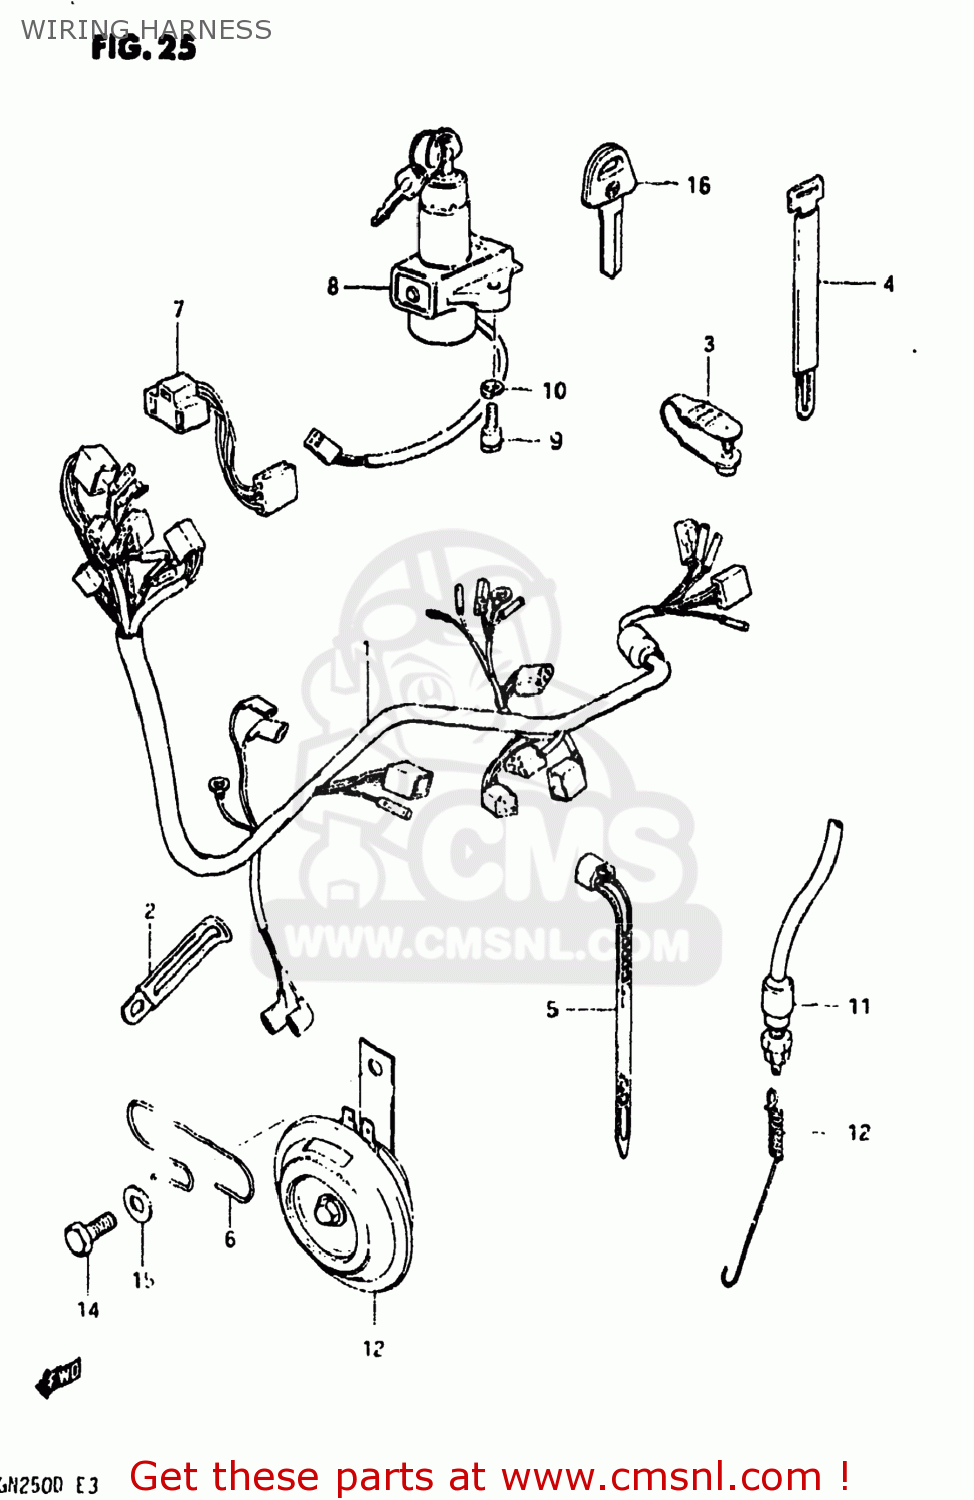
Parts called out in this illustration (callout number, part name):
1	HARNESS,WIRING
2	CLAMP
3	CLAMP,L:88
4	CLAMP
5	CLAMP(L:125)
6	CLAMP,WIRING HARNESS
7	LEAD WIRE,HEADLAMP
8	SWITCH ASSY,IGNITION
9	BOLT
10	LOCK WASHER
11	SWITCH ASSEMBLY,STOP LAMP
12	SPRING
13	HORN ASSEMBLY
14	BOLT
15	WASHER
16	KEY,BLANK
